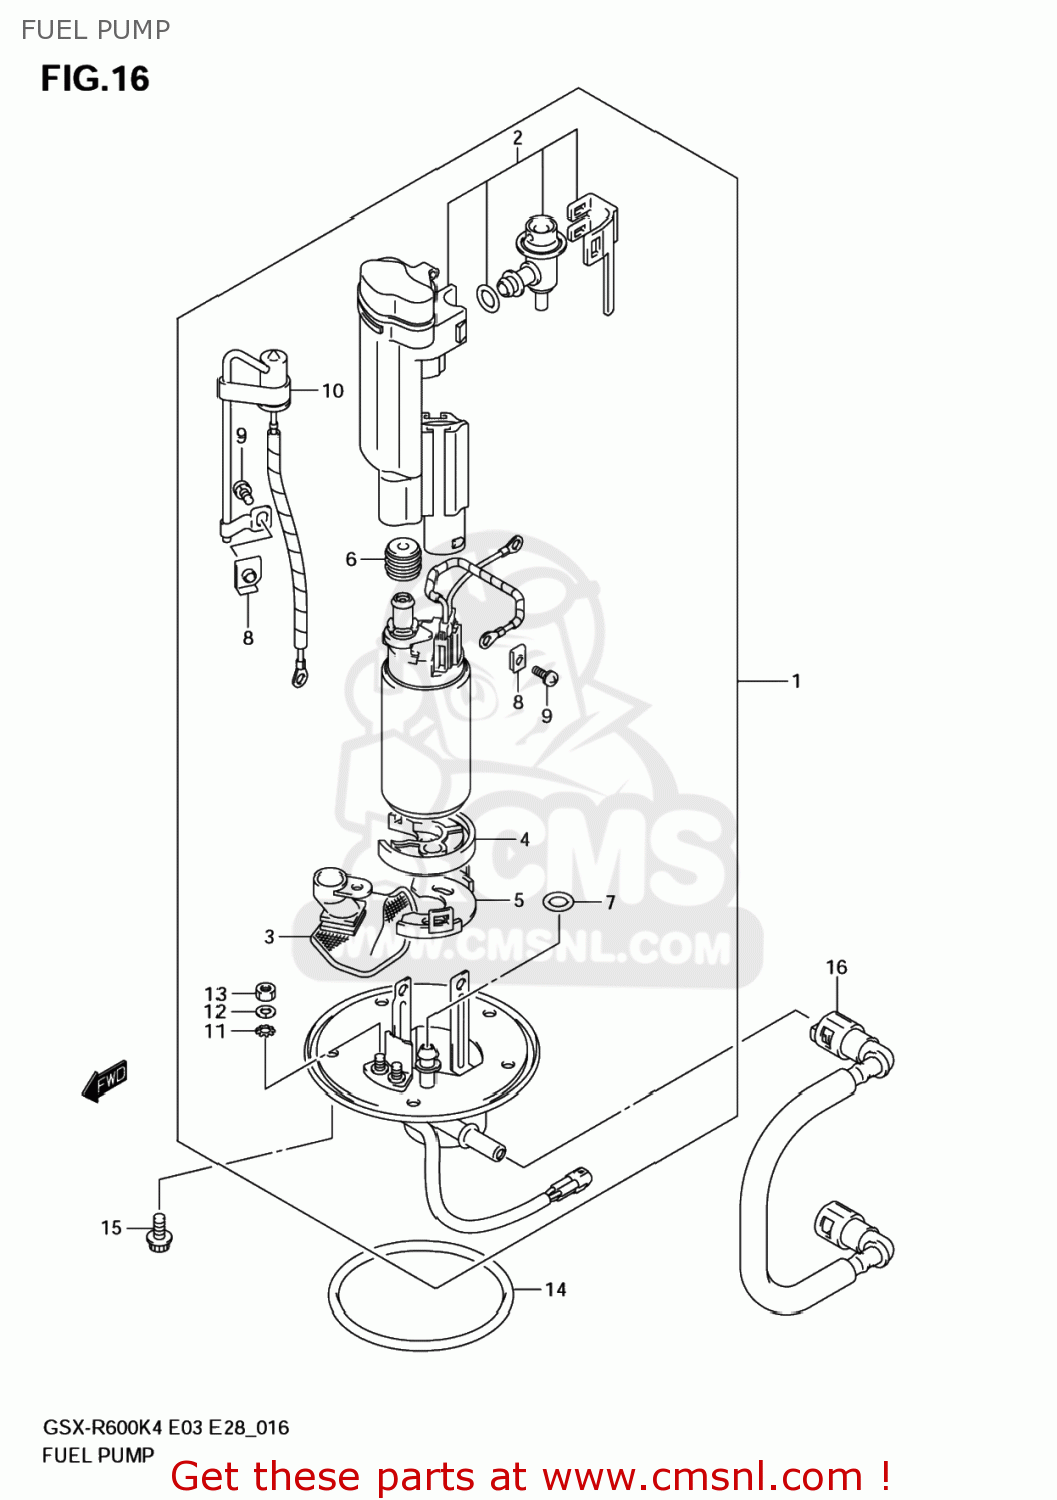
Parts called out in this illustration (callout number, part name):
1	PUMP ASSY,FUEL
2	FILTER ASSY,FUEL
3	STRAINER,FUEL PUMP
4	CUSHION
5	HOLDER,FUEL PUMP
6	BUSH,FUEL PUMP
7	O RING
8	NUT
9	SCREW
10	THERMISTOR
11	WASHER
12	WASHER,SPRING
13	NUT
14	O RING,FUEL PUMP
15	BOLT
16	HOSE,FUEL
